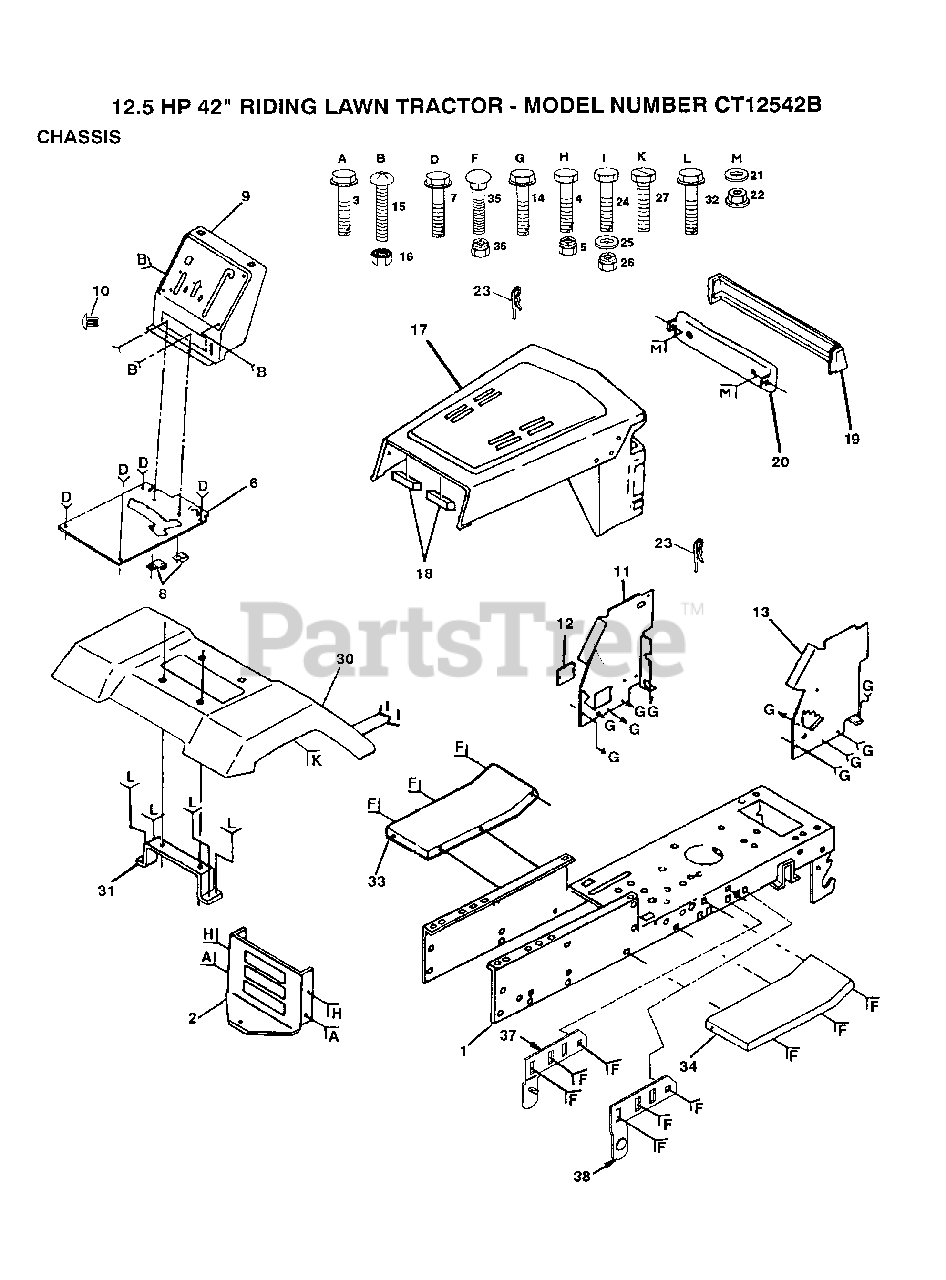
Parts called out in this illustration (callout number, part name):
3	SCREW
7	SCREW LT
8	CLIP T
11	PANEL DASH LH
12	COVER ACCESS
14	SCREW LT
15	SCREW
17	HOOD/GRILL ASM
19	LENS SERVICE KIT
21	WASHER PM
22	PAL NUT LT
23	SPRING.RETAINER
25	WASHER
27	SCREW LT
32	SCREW
33	FOOTREST LH
34	FOOTREST
35	BOLT
37	PIVOT BRKT LH
38	PIVOT BRKT RH
